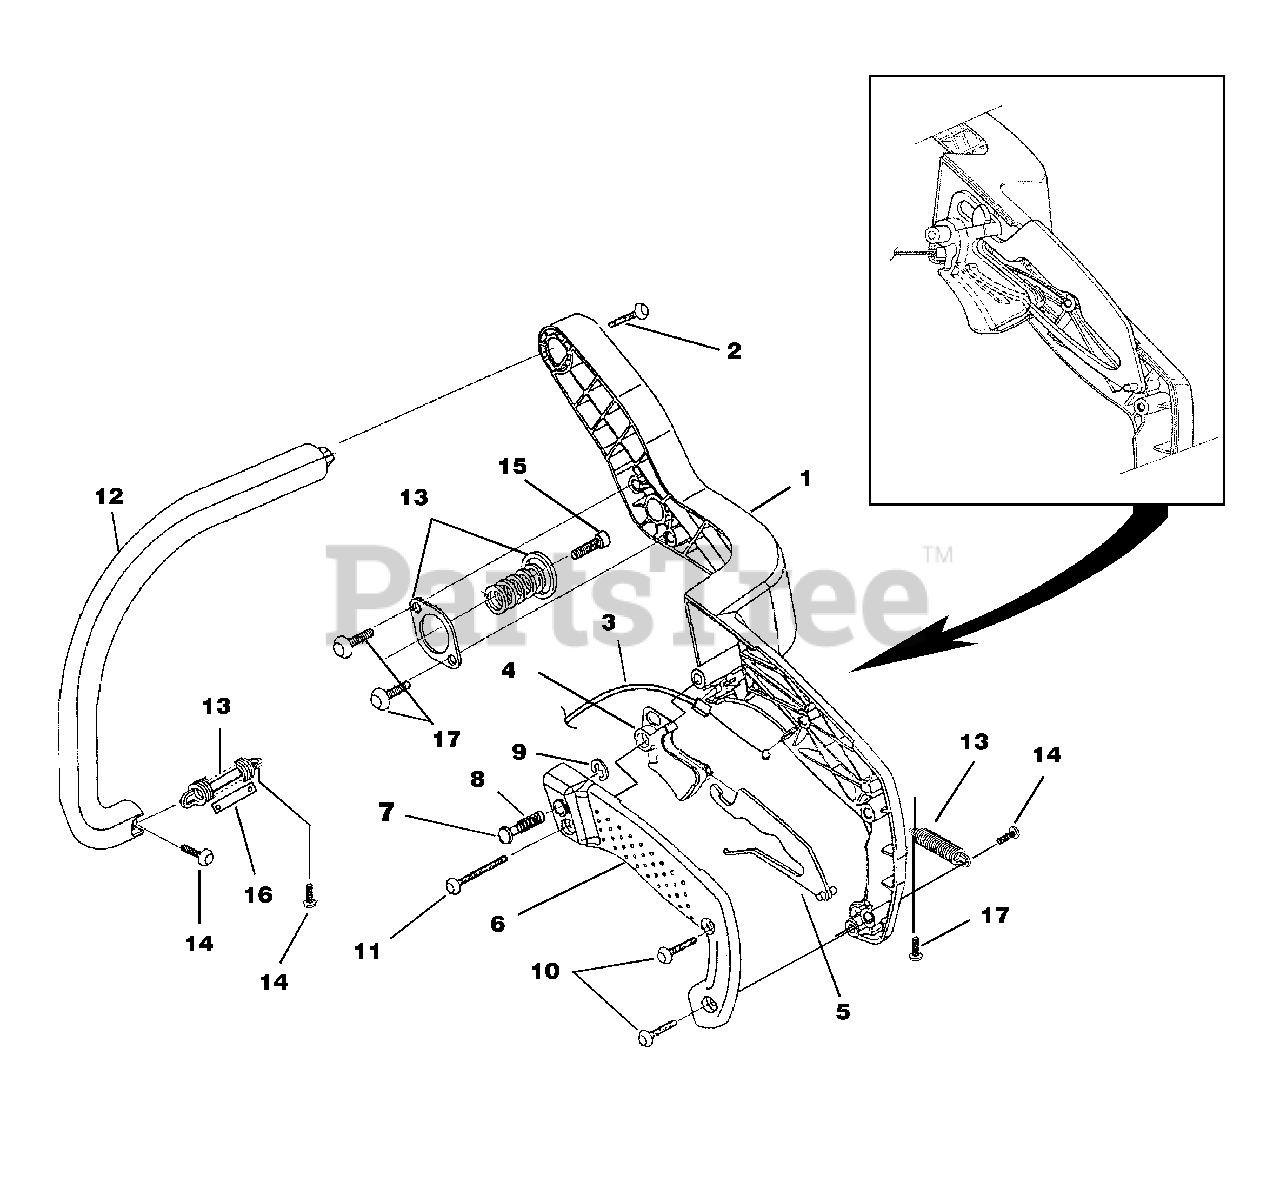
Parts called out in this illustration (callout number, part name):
1	Rear Handle Kit
2	Screw-Pan Hd. (12-14 x 1 1/2")
3	Throttle Cable
4	Trigger, Throttle
5	Throttle Lock Out
6	Handle Cover Kit
7	Throttle Lock Pin
8	Spring, Compression
9	Ring, Retainer
10	Screw, Thread Form (10-14 x 3/4")
11	Screw, Thread Form (10-14 x 1 3/8")
12	Front Handle Kit
13	Isolator Kit
14	Screw, Truss Hd. (10-14 x 5/8")
15	Screw, Truss Hd. (10-24 x 5/8")
16	Limiter, Isolator
17	Screw, Thread Form (10-14 x 1/2")
